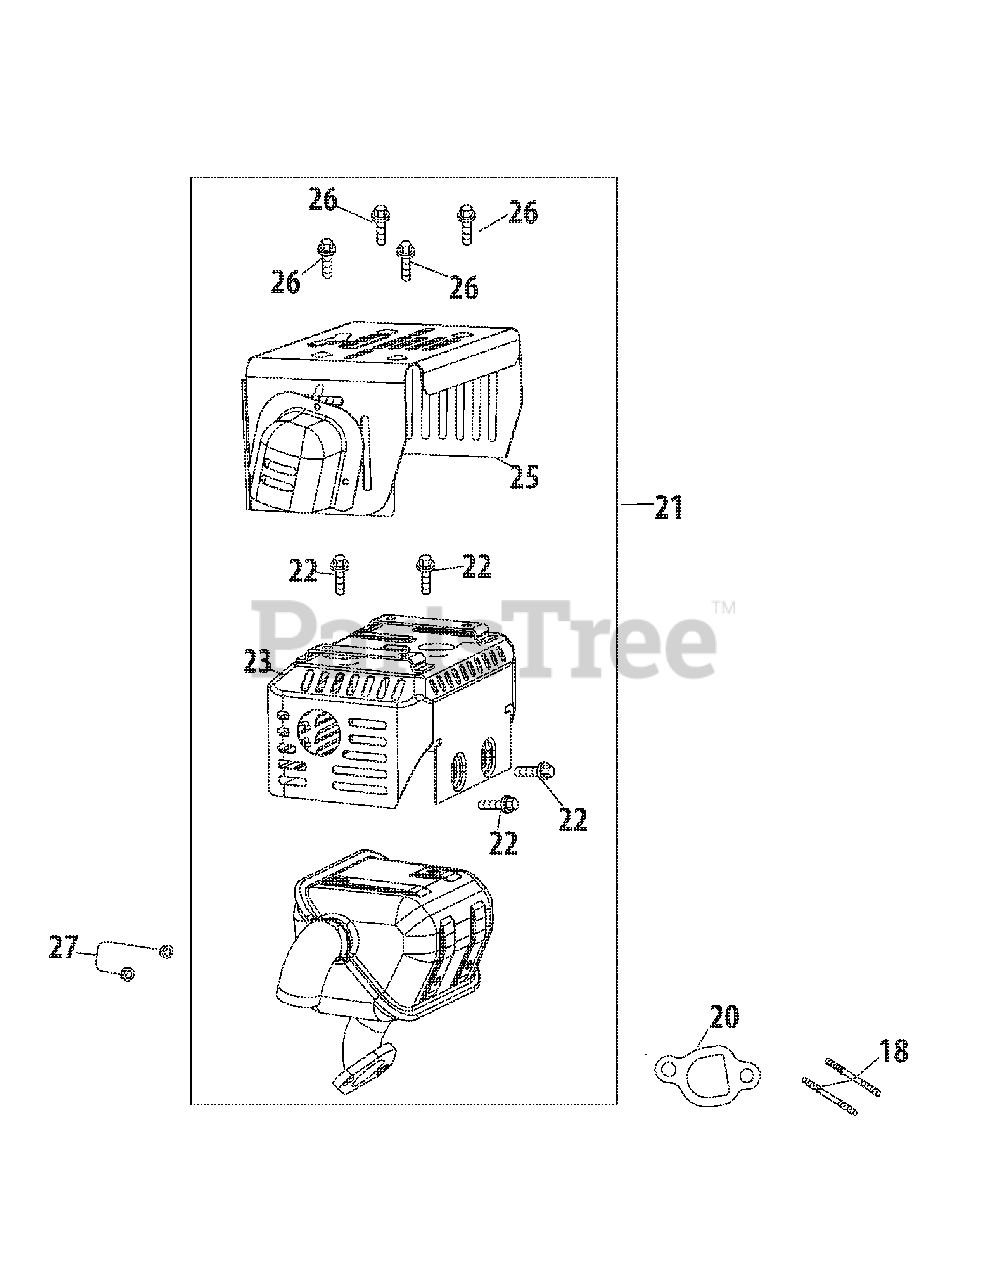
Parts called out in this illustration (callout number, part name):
18	Stud M8×34
20	Muffler Gasket
21	Muffler Assembly
22	Bolt M5×12
23	Muffler Shield
25	Muffler Guard
26	Bolt M5×8
